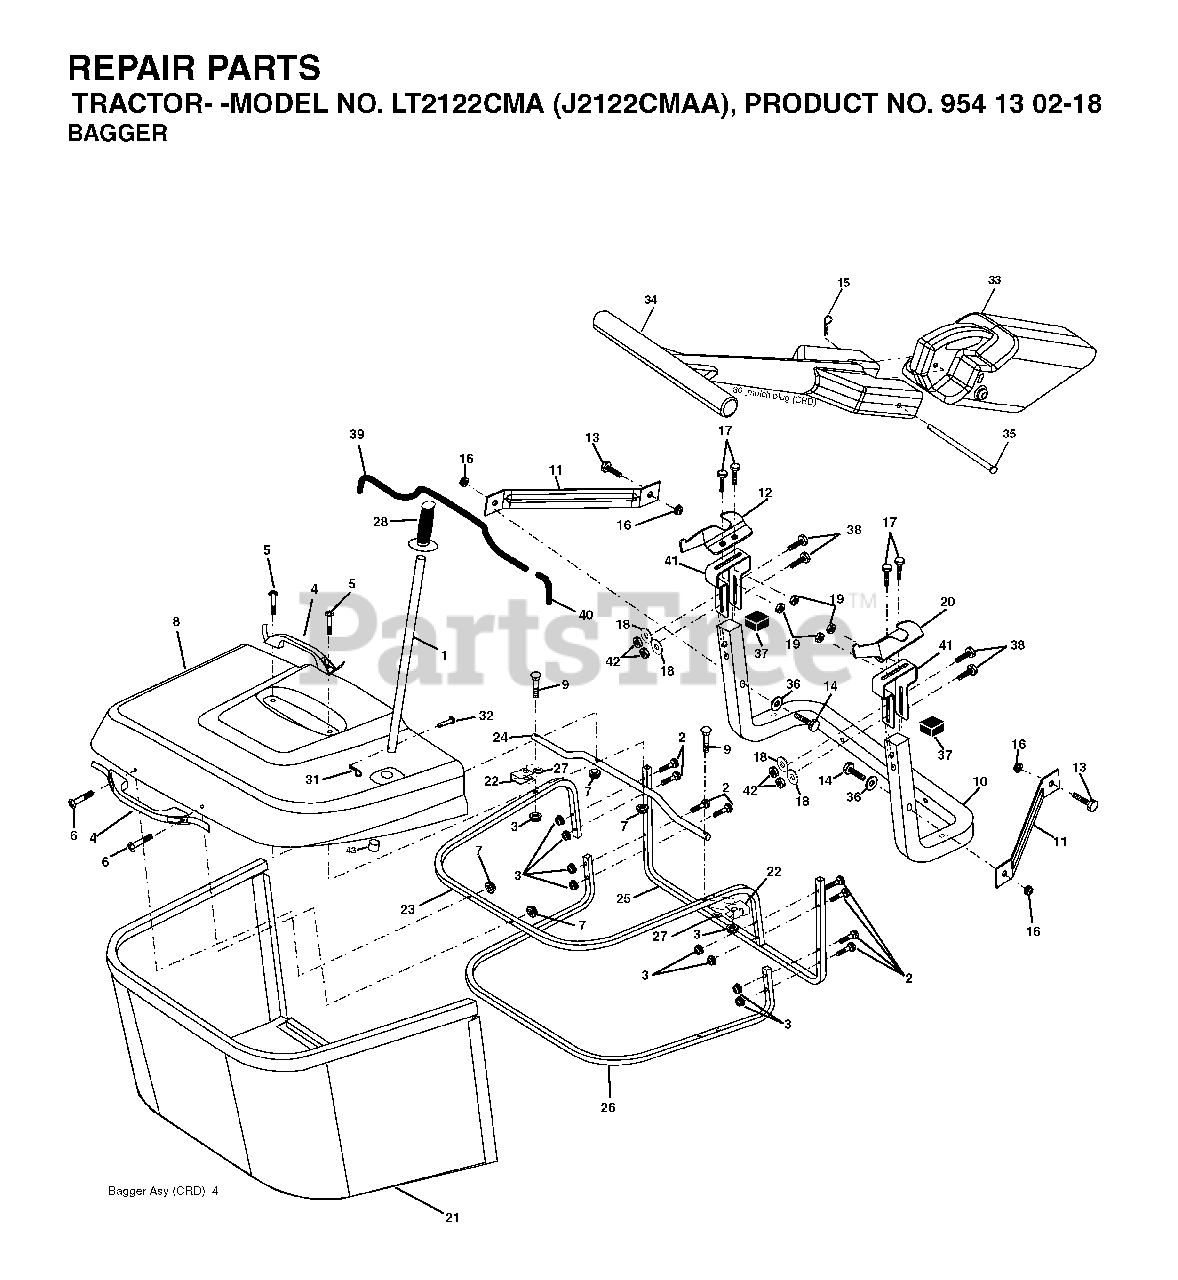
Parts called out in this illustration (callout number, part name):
1	TUBE HANDLE
3	NUT T
5	SCREW.PAN.HEAD
11	BRACKET
14	BOLT-HEX EAK
15	RETAINER-SPRNG RB
16	NUT LOCK FLG 3/8-16 UNC
17	BOLT
18	WASHER M
19	NUT LOCK HEX FLANGE 5/16-18
20	BRACKET
21	GRASS BAG
22	BRACKET
23	TUBE
24	TUBE
26	TUBE
28	GRIP.HANDLE.BLACK
31	RETAINER CLIP
32	RIVET,DRILLED
33	MULCH PLUG, CTH150
35	PIN
36	WASHER
38	BOLT.5/16-18X2.5
41	BRKT, BAGGER
42	NUT.71038.31-18.HEX.NYLOCK
43	PLUG, TUBING END
